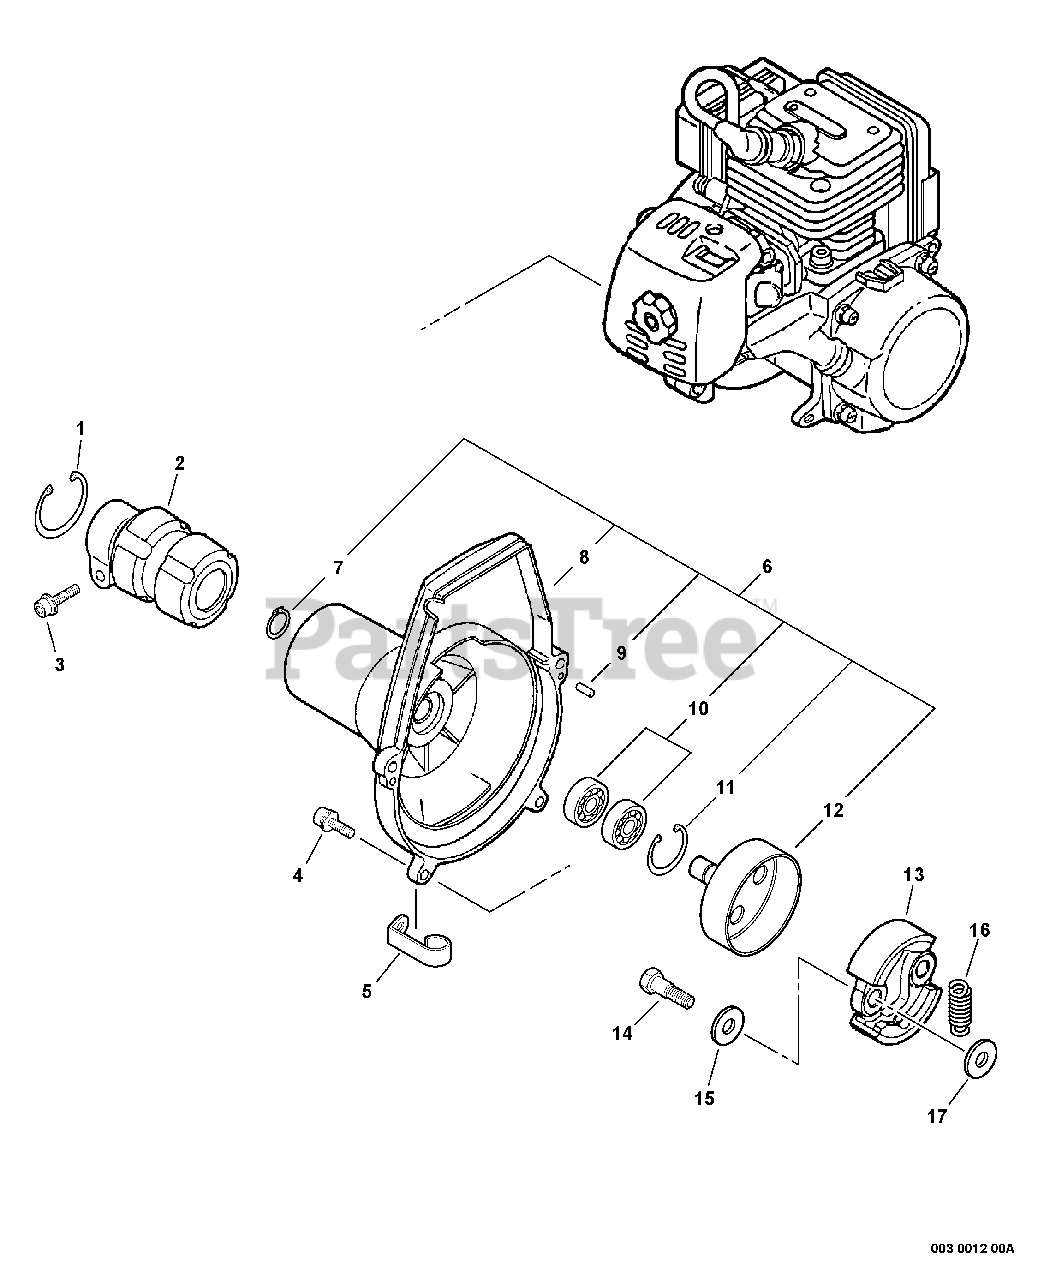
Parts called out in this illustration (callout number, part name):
1	RING, RETAINING - 42
2	CLAMP, MAIN PIPE
3	SCREW - 5X28
4	SCREW - 5X18
6	FAN CASE ASSY
7	RING, RETAINING - 12
8	FAN CASE ASSY - ORANGE
9	PIN - LOCATING
10	BEARING, BALL - 6001
11	RING, RETAINING - 28
12	DRUM, CLUTCH
13	SHOE, CLUTCH
14	BOLT, CLUTCH
15	WASHER - SPRING
16	SPRING, CLUTCH
17	WASHER - 6
